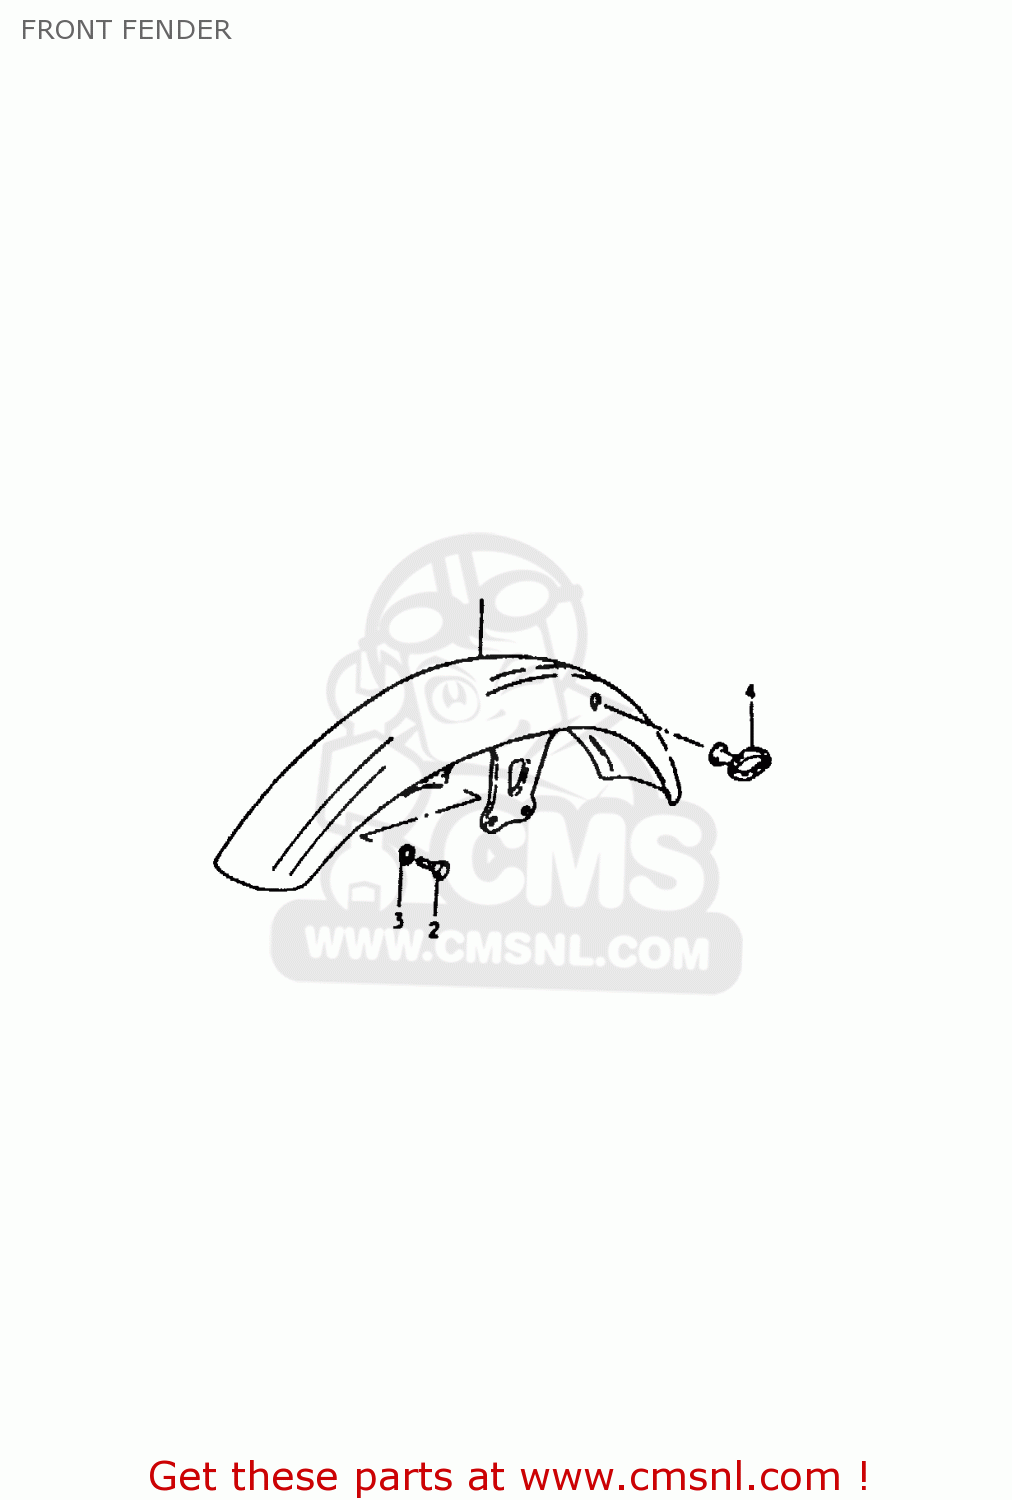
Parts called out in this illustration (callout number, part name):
1	FENDER, FRONT
2	BOLT
3	LOCK WASHER
4	GUIDE,CABLE
